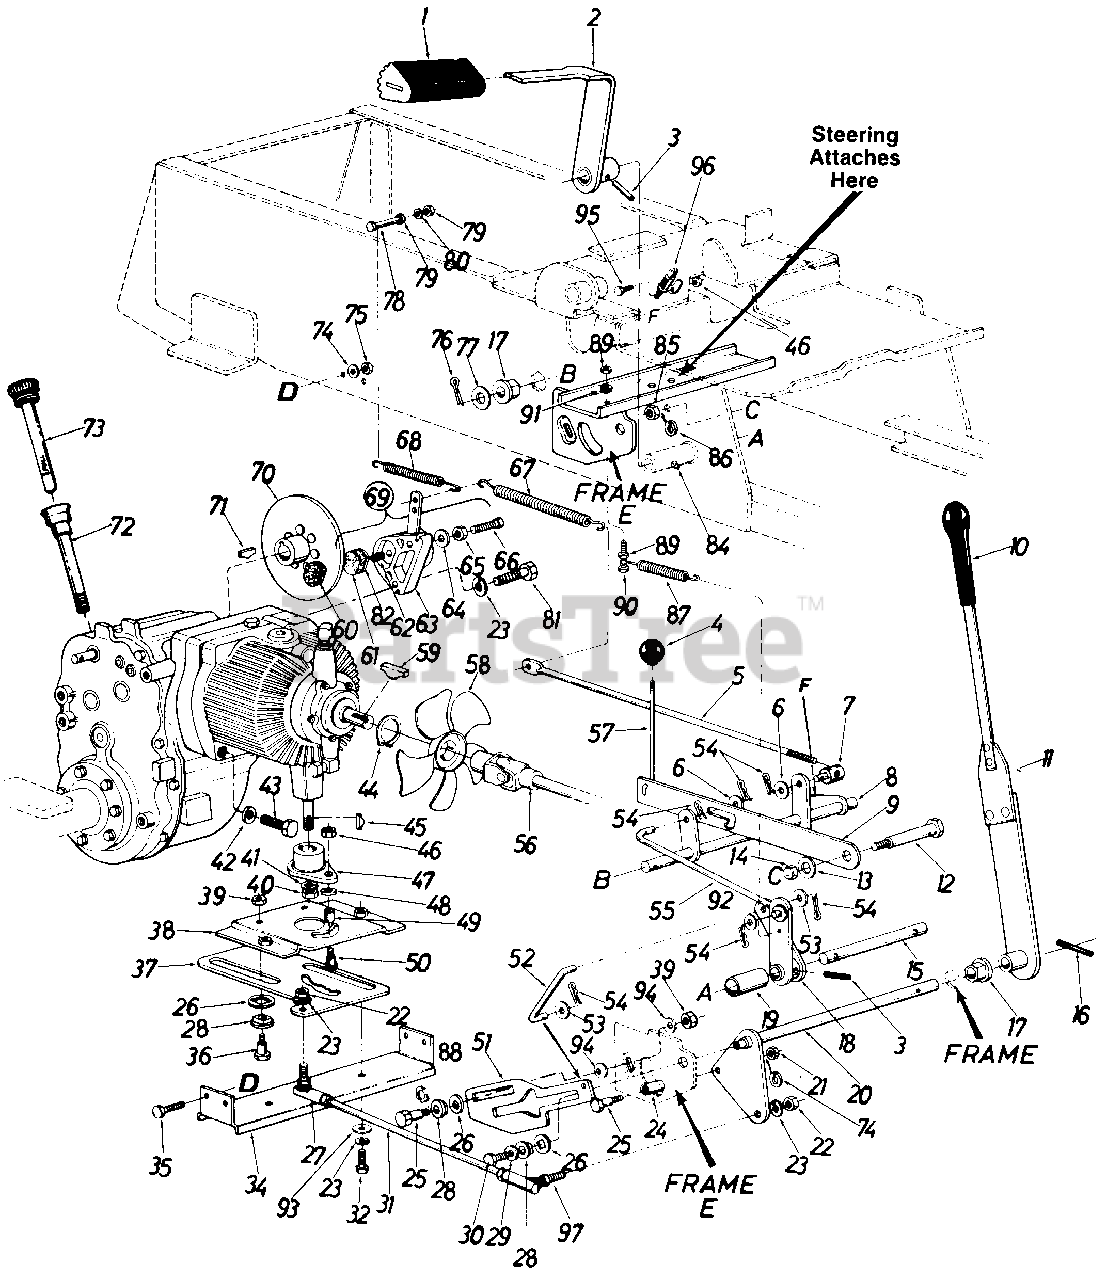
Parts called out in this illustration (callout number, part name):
4	Ball Knob Brake
6	Fl-Wash. .375" I.D. x 1.00" O.D. x .030
7	Ferrule
8	Brake Transfer Shaft Ass'y.
9	Parking Brake Cam
11	Control Arm Ass y. Comp.
12	Shld Scr. .62 Dia. x 2.75" Lg.
13	Fl-Wash. .460 I.D. x 1.24 0 O.D. x .06
14	Push Speed Nut for .625 Dia. Shaft
15	Brake Pivot Shaft
16	Spring Pin Spiral 1/4" Dia. x 1.50" Lg.*
17	Hex Flange Brg. Plastic .62 I.D.
18	Brake Hub Ass'y.
20	Control Handle Ass'y.
21	Hex Cent. L-Nut 5/16-18 Thd.
22	Hex Nut 3/8-24 Thd.*
23	L-Wash. 3/8" Scr.*
25	Shoulder Bolt
26	Fl-Wash. .63 Sq. Hole x 1.25" O.D.
27	Ball Joint Ass'y. 3/8-24 0 Thd. L. H .
29	Fl-Wash. .312 I.D. x .88 O.D.
30	Hex Ins. Scr. 5/16-18 x 1.00" Lg.
31	Tie Rod
32	Hex Scr. 3/8-16 x .75" Lg.*
34	Support Channel
35	Hex Scr. 5/16-18 x .75" Lg.*
36	Shld. Scr. .437" Dia. x .350
38	Slide Mtg. Plate Ass'y.
39	Hex Cent. L-Nut 5/16-18 Thd.
40	Hex Nut 1/2-13 Thd.*
41	L-Wash. 1/2" Scr.*
42	Fl-Wash. .385 I.D. x .87 0 O.D. x .060
43	Socket Hd. Scr. 3/8-16 x 2.75" Lg.
45	#5 Hi-Pro Key 1/8" x 5/8" Dia.
46	Hex Cent. L-Nut 1/4-20 Thd.
47	Pintle Plate Ass'y.
48	Fl-Wash. .281 I.D. x .50 O.D. x .063
49	Needle Brg. .31" I.D. x .50" O.D. x .437" Lg.
50	Shld. Scr. .31 Dia. x .500 0
51	Neutral Control Slide
52	Neutral Control Rod
53	Fl-Wash. .312 I.D. x .630 0 O.D. x .063
54	Hairpin Cotter
55	Brake Link Rod Ass'y.
56	Universal Joint Ass'y. Comp.
57	Parking Brake Link
58	Fan Ass'y.
59	#61 Hi-Pro Key 3/16 x 5/8" Dia.
60	Lining Brake
61	Lining Brake
63	Housing with Lever and Pin
64	Washer
65	Nut
66	Adjustment Pin
67	Extension Spring .59 O.D. x 6.5" Lg.
68	Extension Spring
69	Disc Brake Ass'y. Comp.
70	Brake Disc Ass'y.
71	Hi-Pro Key 3/16 x 3/4" Dia.
72	Dipstick Tube Ass'y.
73	Dipstick Ass'y.
74	L-Wash. 5/16" Scr.
75	Hex Nut 5/16-18 Thd.
76	Cotter Pin 1/8" Dia. x 1.00" Lg.
77	Fl-Wash. .635" I.D. x 1.00 O.D. x .120 Thk.
78	Hex Scr. 1/4-20 x 2.50" Lg.
79	Hex Nut 1/4-20 Thd.
80	L-Wash. 1/4" Scr.
81	Hex Scr. 3/8-16 x 1.25" Lg.
82	Backing Plate
84	Grease Fitting
85	Hex Nut 7/16-20 Thd.,
86	L-Wash. 7/16" Scr.
87	Extension Spring
88	Wave Wash.
89	Hex Nut 1/4-20 Thd.
90	Hex Scr. 1/4-20 x 1.25" Lg.
91	L-Wash. 1/4" Scr.
92	Fl-Wash.
93	Fl-Wash. .38 I.D. x 1.25 O.D.
95	Hex Scr. 1/4-20 x 1/2" Lg.
96	Safety Switch
97	Ball Joint Ass'y. 3/8-24 Thd . R . H .
